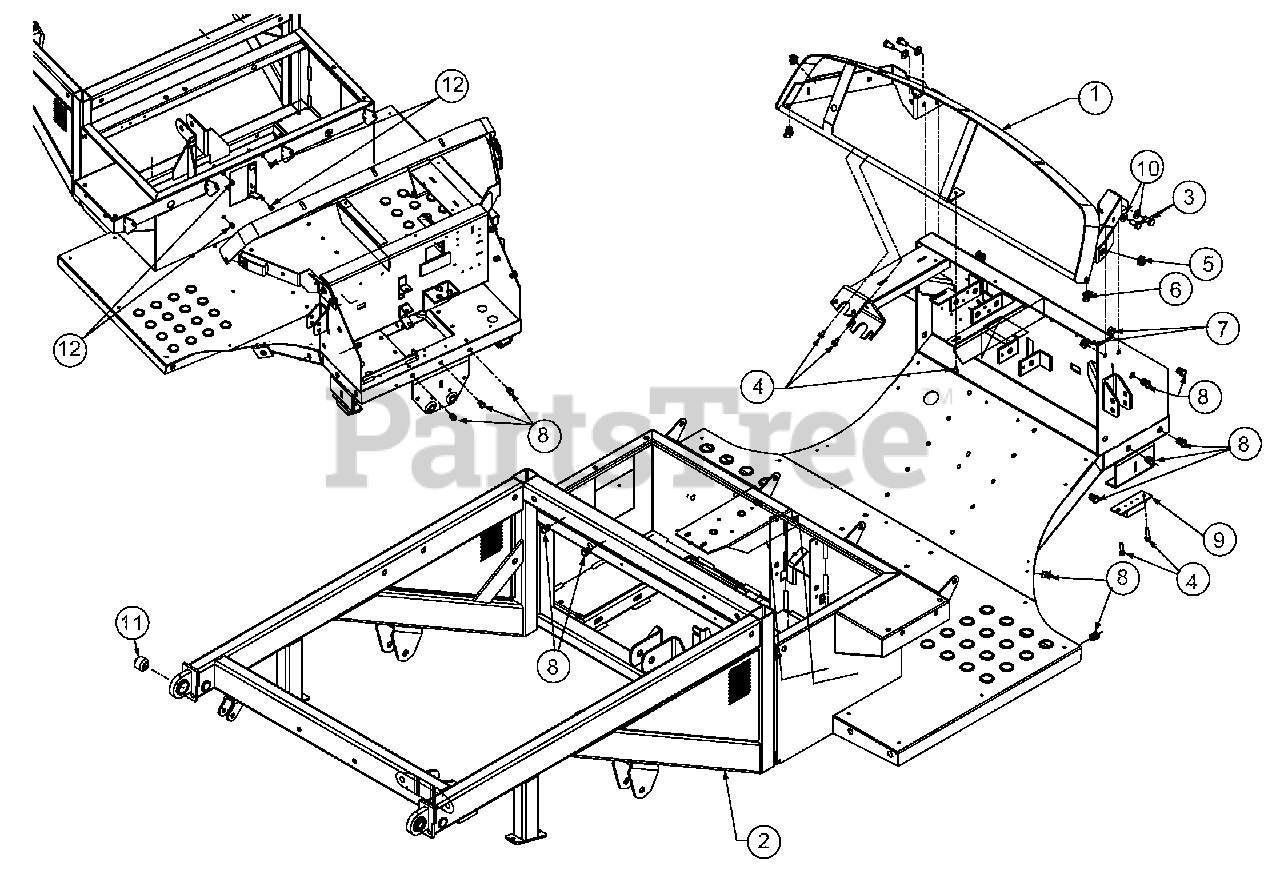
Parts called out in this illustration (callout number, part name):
3	Screw, Hex, 3/8-16 x .75
4	Screw, Self-tapping, 1/4-20 x 0.500
5	Nut, Retainer, 5/16-18
6	U-Nut, 1/4-20
7	Nut, Flange Lock, 3/8-16
8	Nut, Insert, 5/16-18
9	Bumper, Compression Extension
10	Washer, Flat, .406 x 812 x .51
11	Rubber Bushing, Bed Pivot
12	Insert 1/4-20
